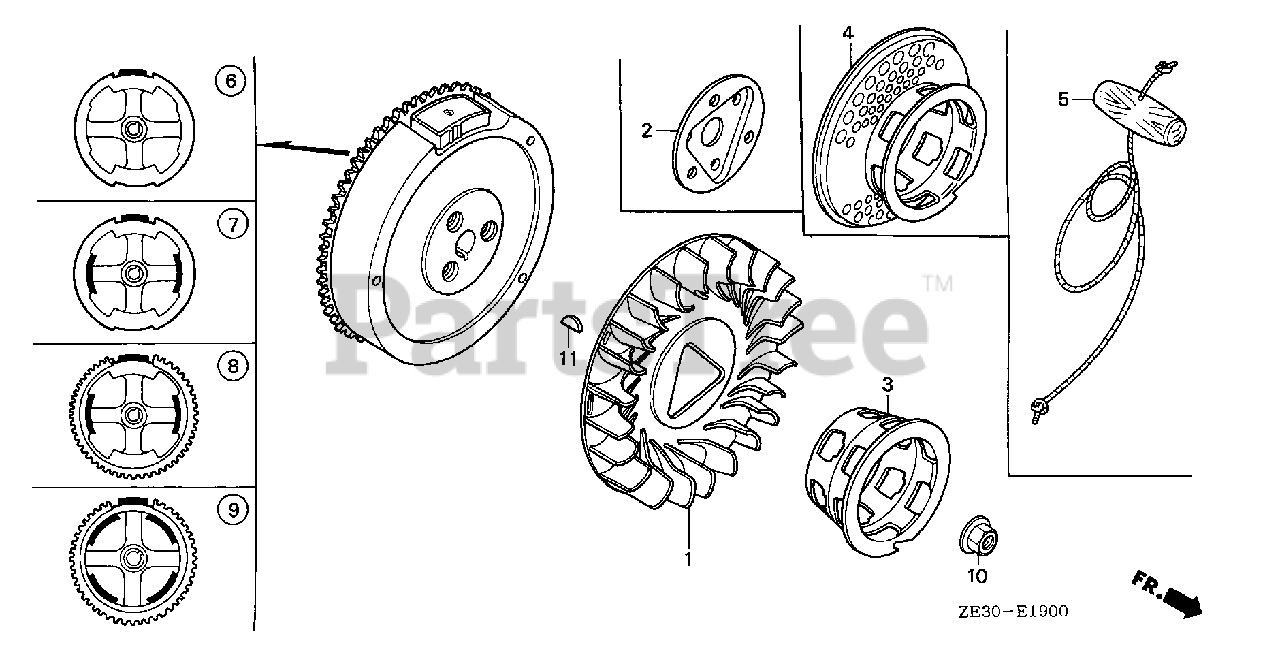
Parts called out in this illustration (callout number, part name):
1	FAN, COOLING
4	PULLEY, STARTER (SCREEN GRID) (NOT AVAILABLE)
6	FLYWHEEL (NOT AVAILABLE)
10	NUT, SPECIAL (16MM)
11	KEY, SPECIAL WOODRUFF (25X18)
